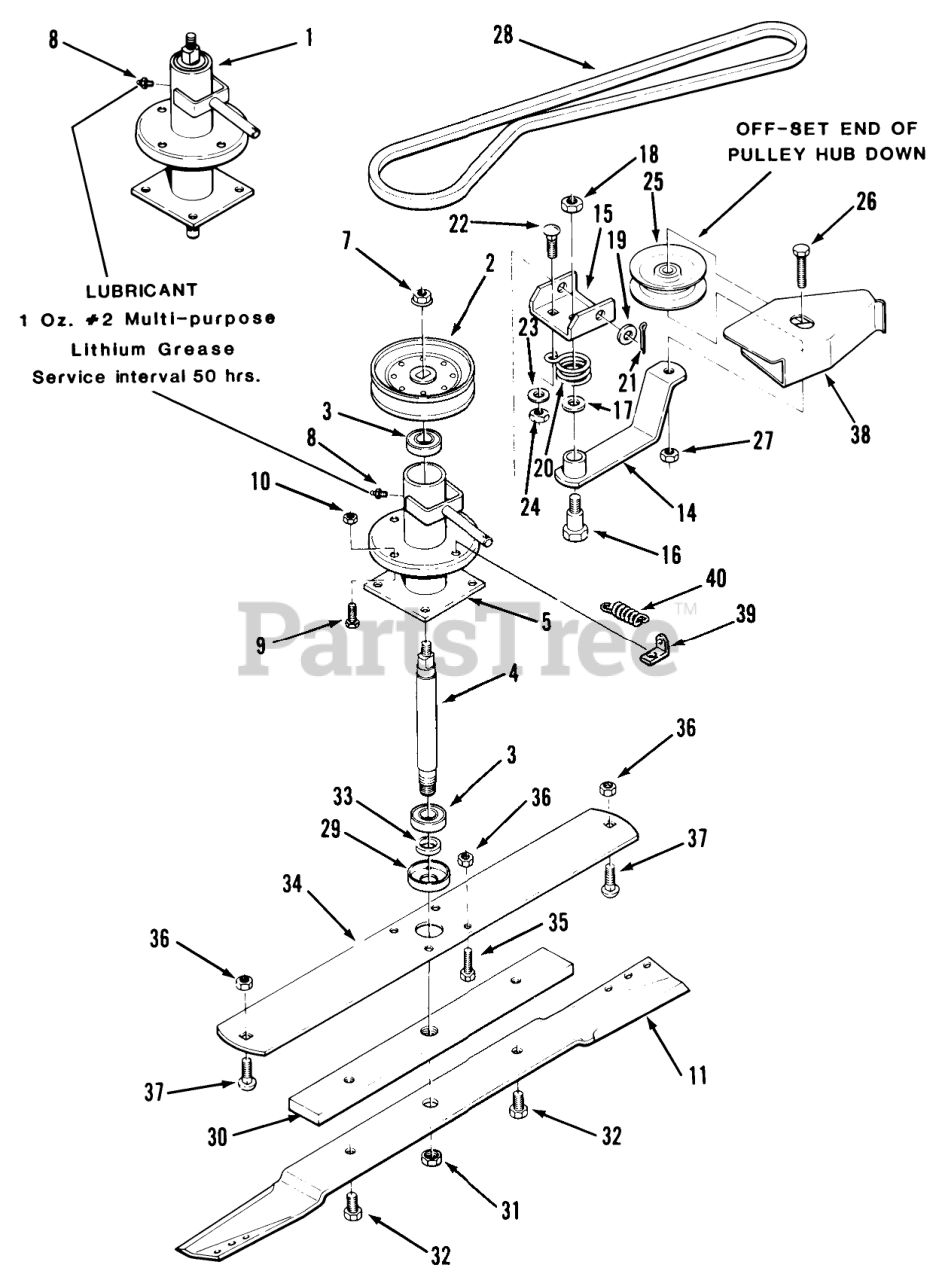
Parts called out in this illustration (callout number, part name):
1	Spindle Assy Complete
2	PULLEY SPINDLE
3	BALL BEARING
4	SHAFT SPINDLE
5	Spindle Housing
7	NUT 3/8-24 WHIZLOCK
8	Zerk
9	Bolt
10	Nut
11	Blade
14	ASSY LEVER R
15	CHANNEL PIVOT R
16	BOLT-SHOULDER
17	WASHER
18	NUT-JAM(7/16-14)
19	Washer
20	SPRING-TORSION
21	Cotter Pin
22	Bolt
23	Washer
24	NUT
25	PULLEY IDLER R
26	Bolt
27	NUT
28	Mower Drive Belt
29	CUP SPINDLE
30	BAR BLADE R
31	Nut
32	HEX BOLT 1/2-13X3/4
33	SPACER-BLADE
34	PLATE SUPPORT R
35	BOLT
36	NUT
37	Carriage Bolt 3/8-16 X 3/4
38	Belt Cover
39	CLIP - SPRING
40	SPRING-EXTENSION
